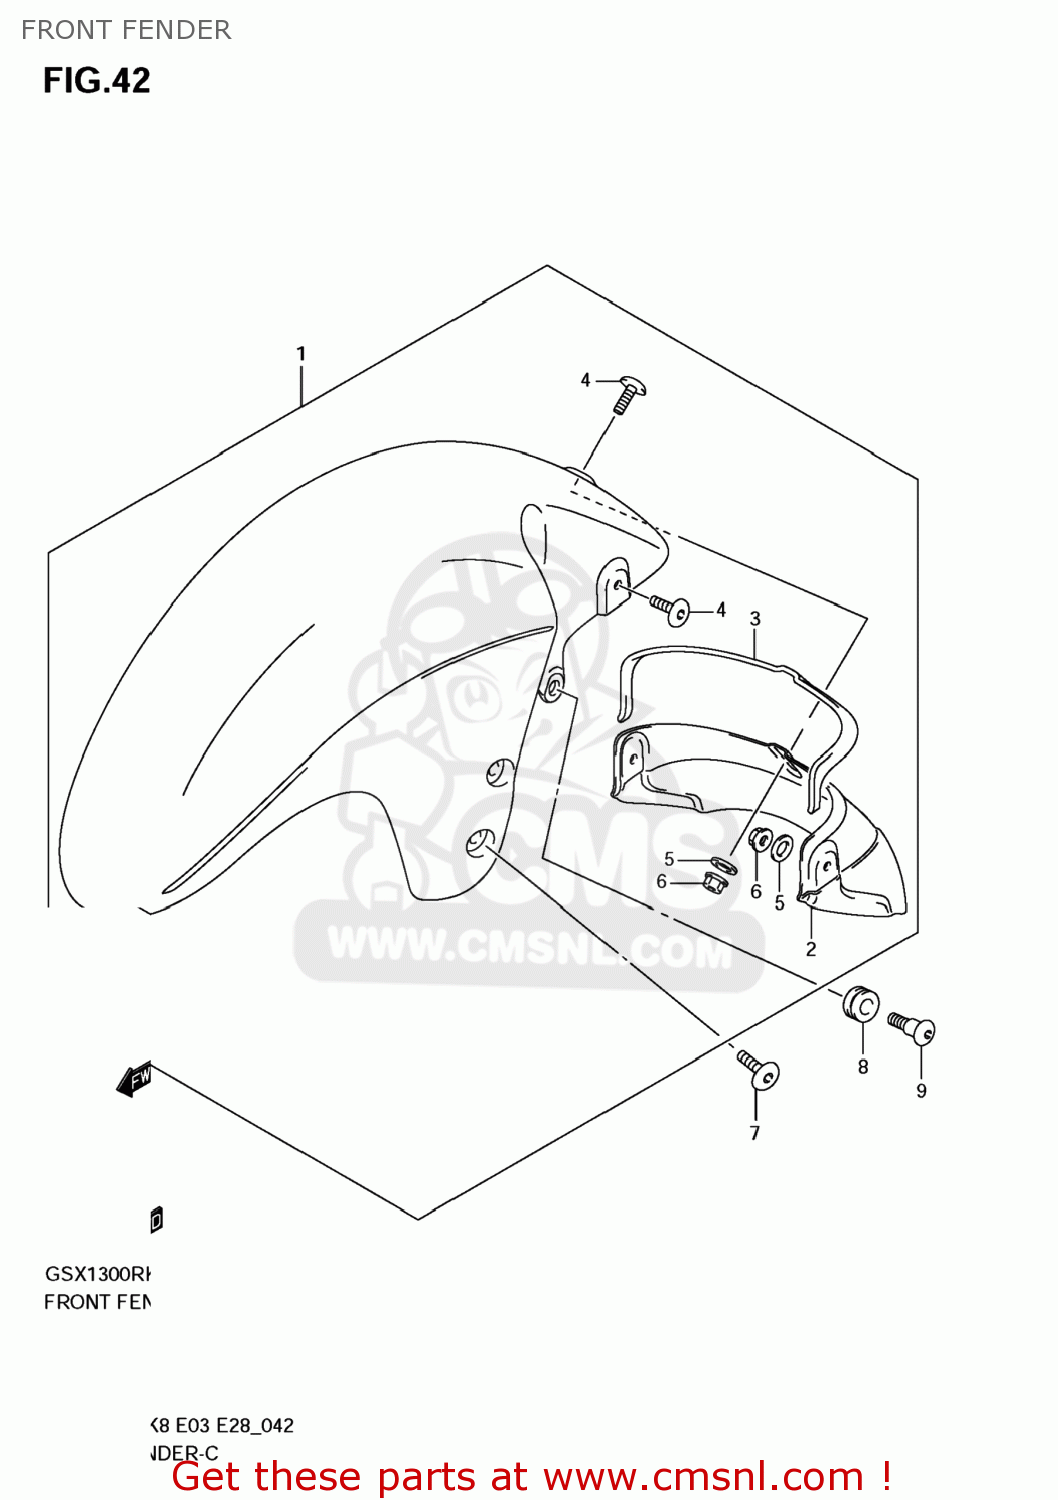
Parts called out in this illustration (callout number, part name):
1	FENDER ASSY,FR(BLACK)
2	MUDGUARD,FR FENDER
3	CUSHION
4	SCREW(6X16)
5	WASHER(6.5X16X1)
6	NUT
7	SCREW(6X16)
8	CUSHION
9	SCREW(6X16)
